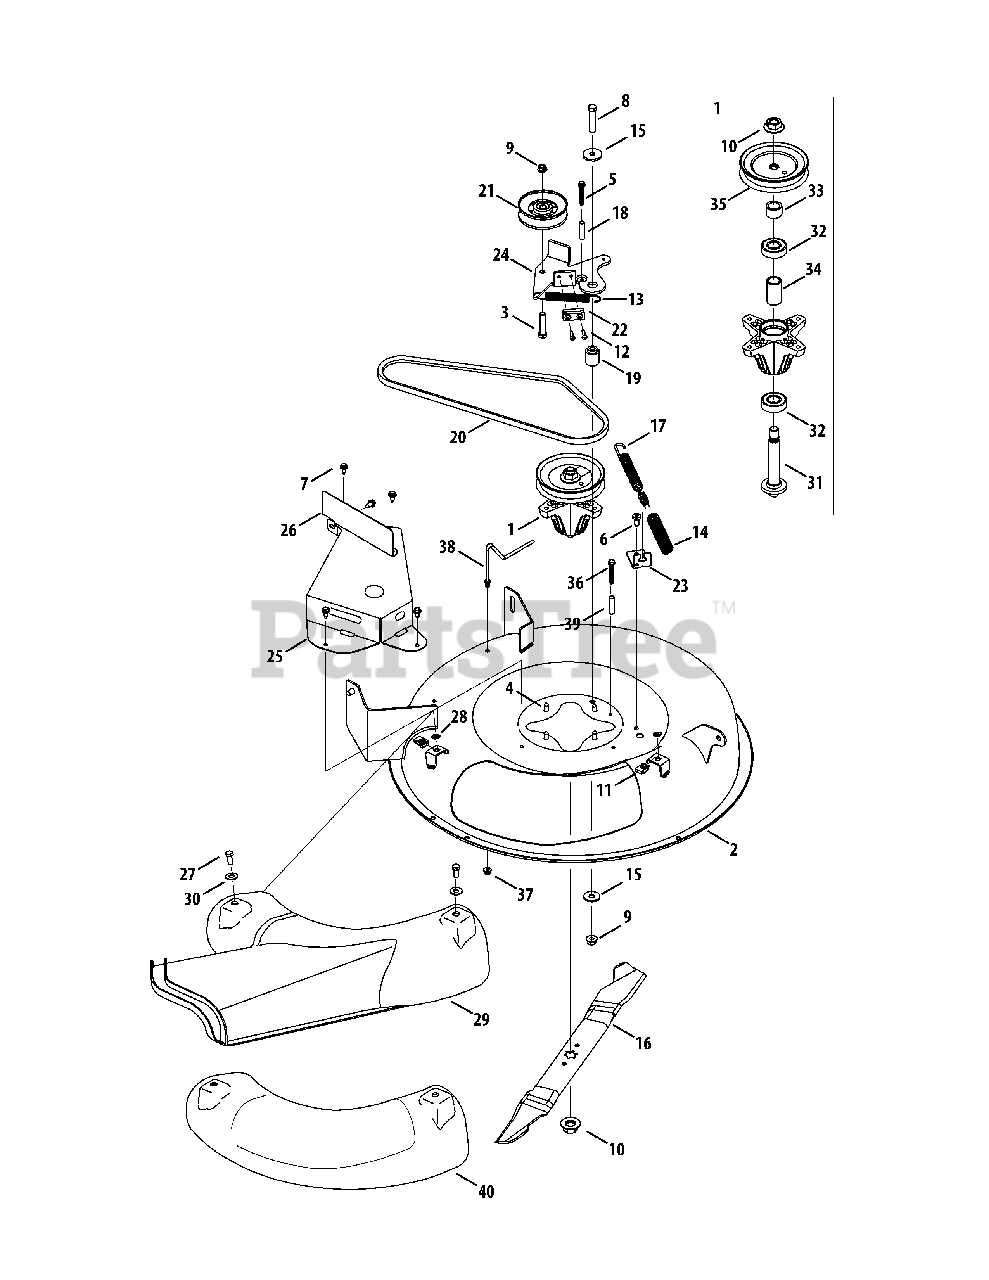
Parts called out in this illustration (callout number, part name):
1	Spindle Pulley Assembly, 5.0 DIA
2	Deck, 24"
3	Hex Cap Screw, 3/8-16 x 1.75
4	Tap Screw, 5/16-18, .750
5	Tap Screw, 1/4-20, 1.750
6	Screw, 5/16-18 x .75
7	Tap Screw, 1/4-20 X .625
8	Hex Cap Screw, 3/8-16 x 2.0
9	Flange Lock Nut, 3/8-16
10	Flange Nut, 5/8-18
11	U-Nut 5/16-18
12	Pop Rivet
13	Extension Spring, .53 OD x 4.75
14	Compression Spring, .625 x 4.0
15	Flat Washer, .38 x 1.38 x .12
16	Blade, 24" 3-IN-1
17	PTO Cable
18	Spacer, .260 X .372 X 1.420 LG
19	Shoulder Spacer, 18MM x 5.0MM
20	V-Type Belt, 43.5 LG
21	Pulley, 3.54 Dia.
22	Spindle Pad
23	Deck Cable Engagement Bracket
24	Deck Idler Bracket
25	Deck Belt Cover
26	Deck Shield
27	Screw, 5/16-18 x .75
28	Speed Nut, .3125
29	Discharge Chute
30	Flat Washer, .406 x .875 x .059
31	Spindle Shaft, 5.25 LG
32	Ball Bearing, .787ID X 1.85 ODX.551
33	Spacer, .820 x 1.15 x .730
34	Spacer, .792 X 1.060 X 1.860 LG
35	Pulley 5.0" Dia.
36	Tap Screw, 1/4-20:1.500
37	Flange Lock Nut, 1/4-20
38	Belt Keeper
39	Spacer, .260 x .375 x 1.030 LG
40	Mulch Plug
